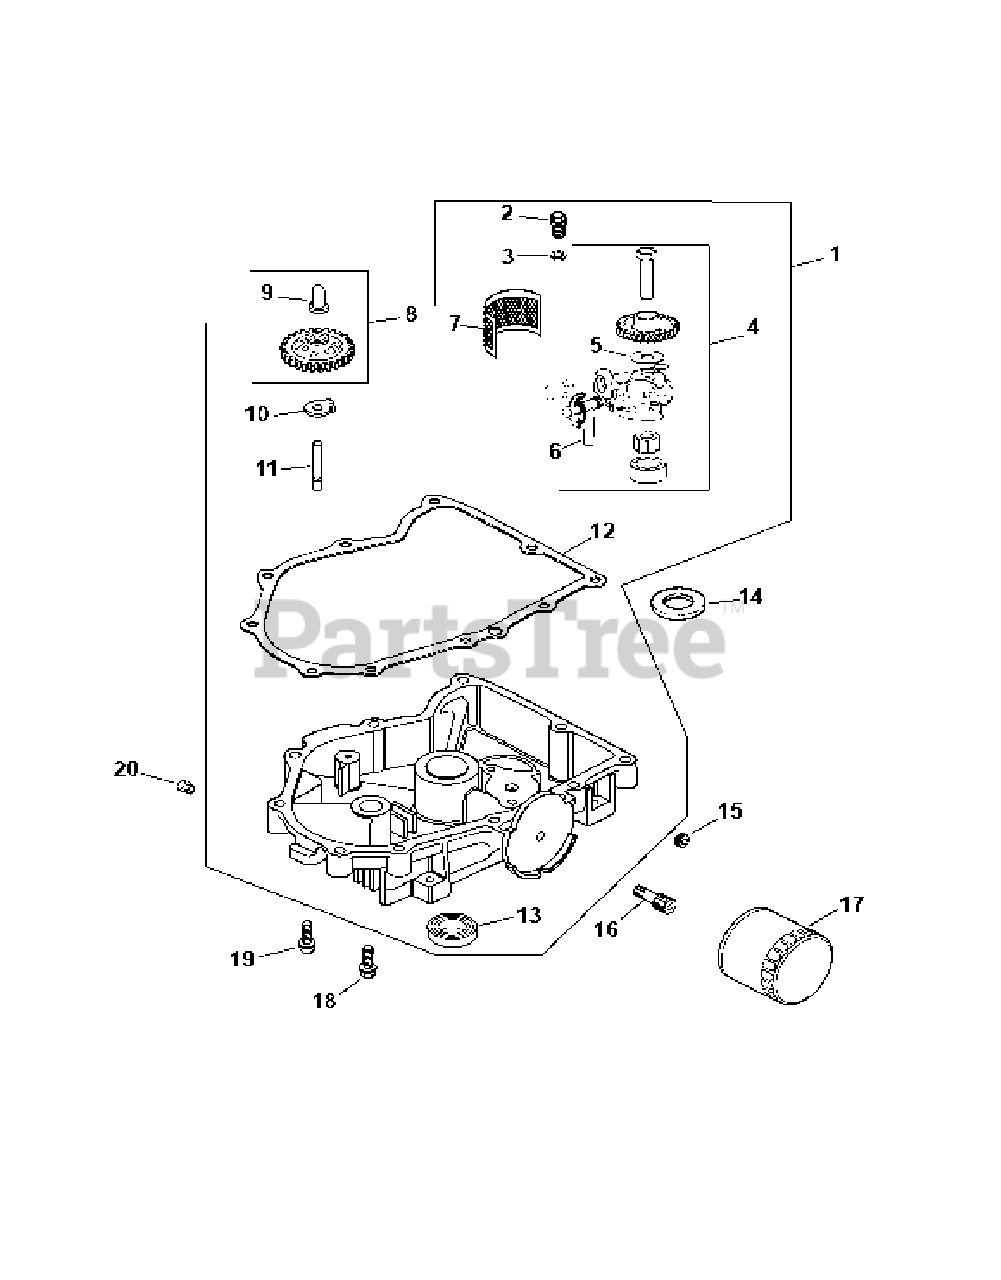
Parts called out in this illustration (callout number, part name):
1	Oil Pan w/Gasket Kit
2	Screw
4	Oil Pump Kit
6	Oil Pickup Tube
8	Governor Gear w/Pin Kit
11	Governor Gear Shaft
12	Oil Pan Gasket
13	Seal
16	Oil Filter Nipple
17	Oil Filter
18	Hex Flange Screw
19	Hex Flange Screw (M6 x 1.0 x 25)
